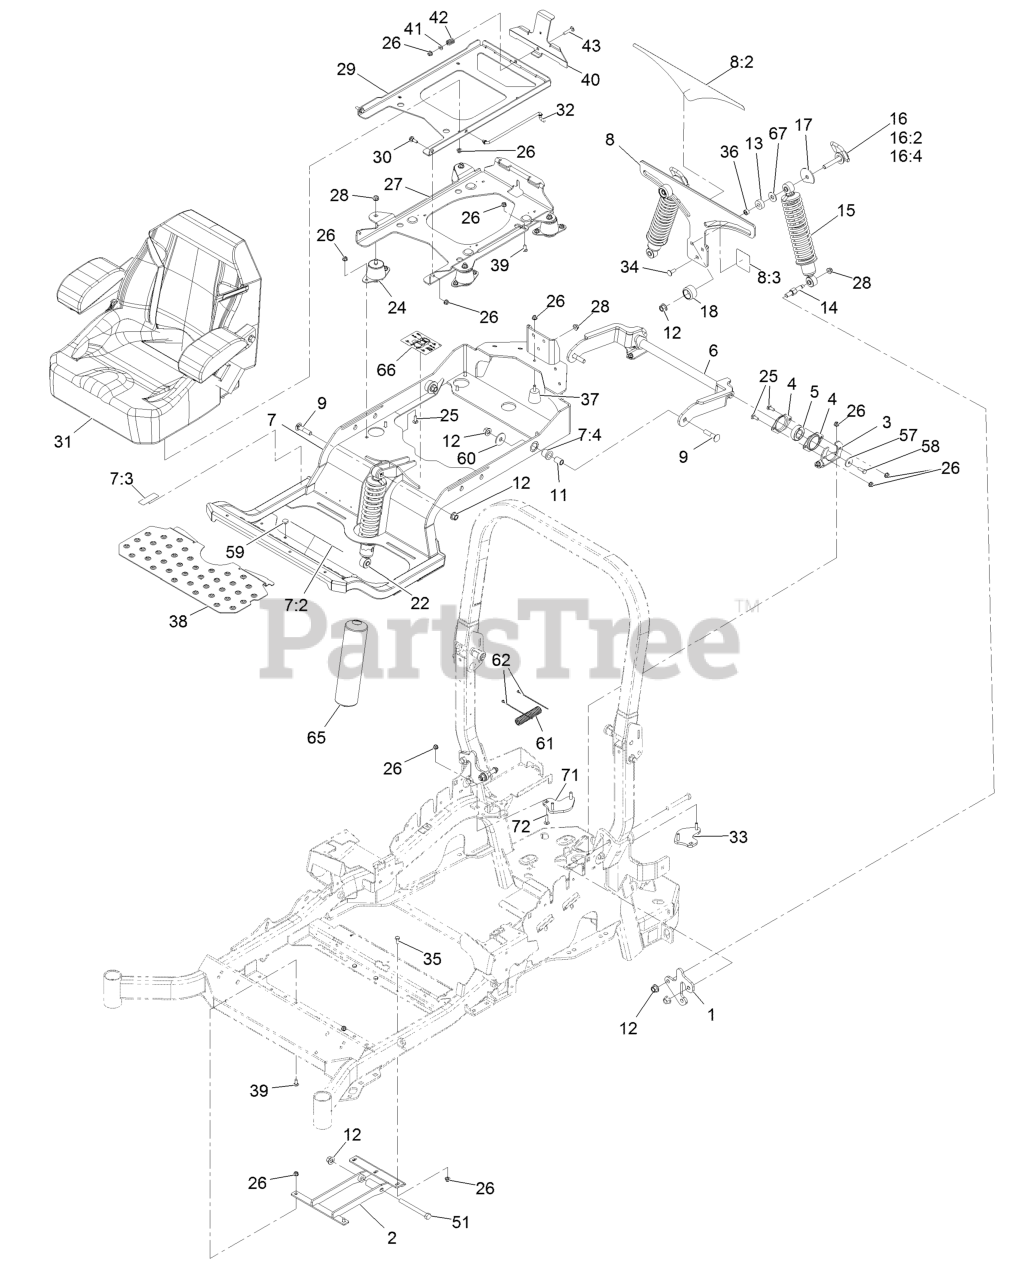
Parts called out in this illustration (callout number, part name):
1	PLATE-MOUNT, SHOCK
2	MOUNT-LOWER
3	BRACKET-BEARING
4	HOUSING-BEARING, FLANGE
5	BEARING
6	ARM-TRAILING
7	SUBFRAME ASM
7:2	DECAL-DANGER
7:3	DECAL-BRAKE, PARKING
7:4	BUSHING-FLANGE
8	BRACKET-MOUNTING
8:2	DECAL-ADJUSTMENT, RIDE
8:3	DECAL-LOCK, CAM
9	SCREW-CARR
11	SPACER-ALUMINUM
12	Nut-Lock 1/2-13
14	BOLT-SHOULDER
15	SHOCK/SPRING ASM
16	CAM LOCK ASM
16:2	CAP-LOCK
16:4	NUT-HEX
17	PLATE-STOP
18	KNOB-FRONT
22	SHOCK/SPRING ASM
24	ISOLATOR-SEAT
25	BOLT-CARR
26	NUT-HF, NI
27	PLATE-SUPPORT, ISO SEAT
28	NUT-HF, NI
29	PLATE-FRAME, SEAT
30	SCREW-SHOULDER
31	SEAT-EXMARK STANDARD
32	ROD-PROP
33	LH PLATE ASM (W/STUDS)
34	SCREW-CARR
35	SCREW-HH
36	BEARING-NEEDLE
37	BUMPER-RUBBER
39	SCREW-CARR
40	PLATE-LATCH,SEAT
41	WASHER-PLAIN
42	SPRING-COMPRESSION
43	BOLT-CARR
51	SCREW-HH
57	WASHER-FLAT
58	SCREW-HH, THREAD LOCKING
60	WASHER-THRUST
61	COVER-HOSE
62	TIE-CABLE
65	COVER-SHOCK
66	DECAL-SERVICE AID
67	WASHER-FLAT
71	RH PLATE ASM (W/STUDS)
72	Bolt-Carriage 5/16-18 X 1 1/4
